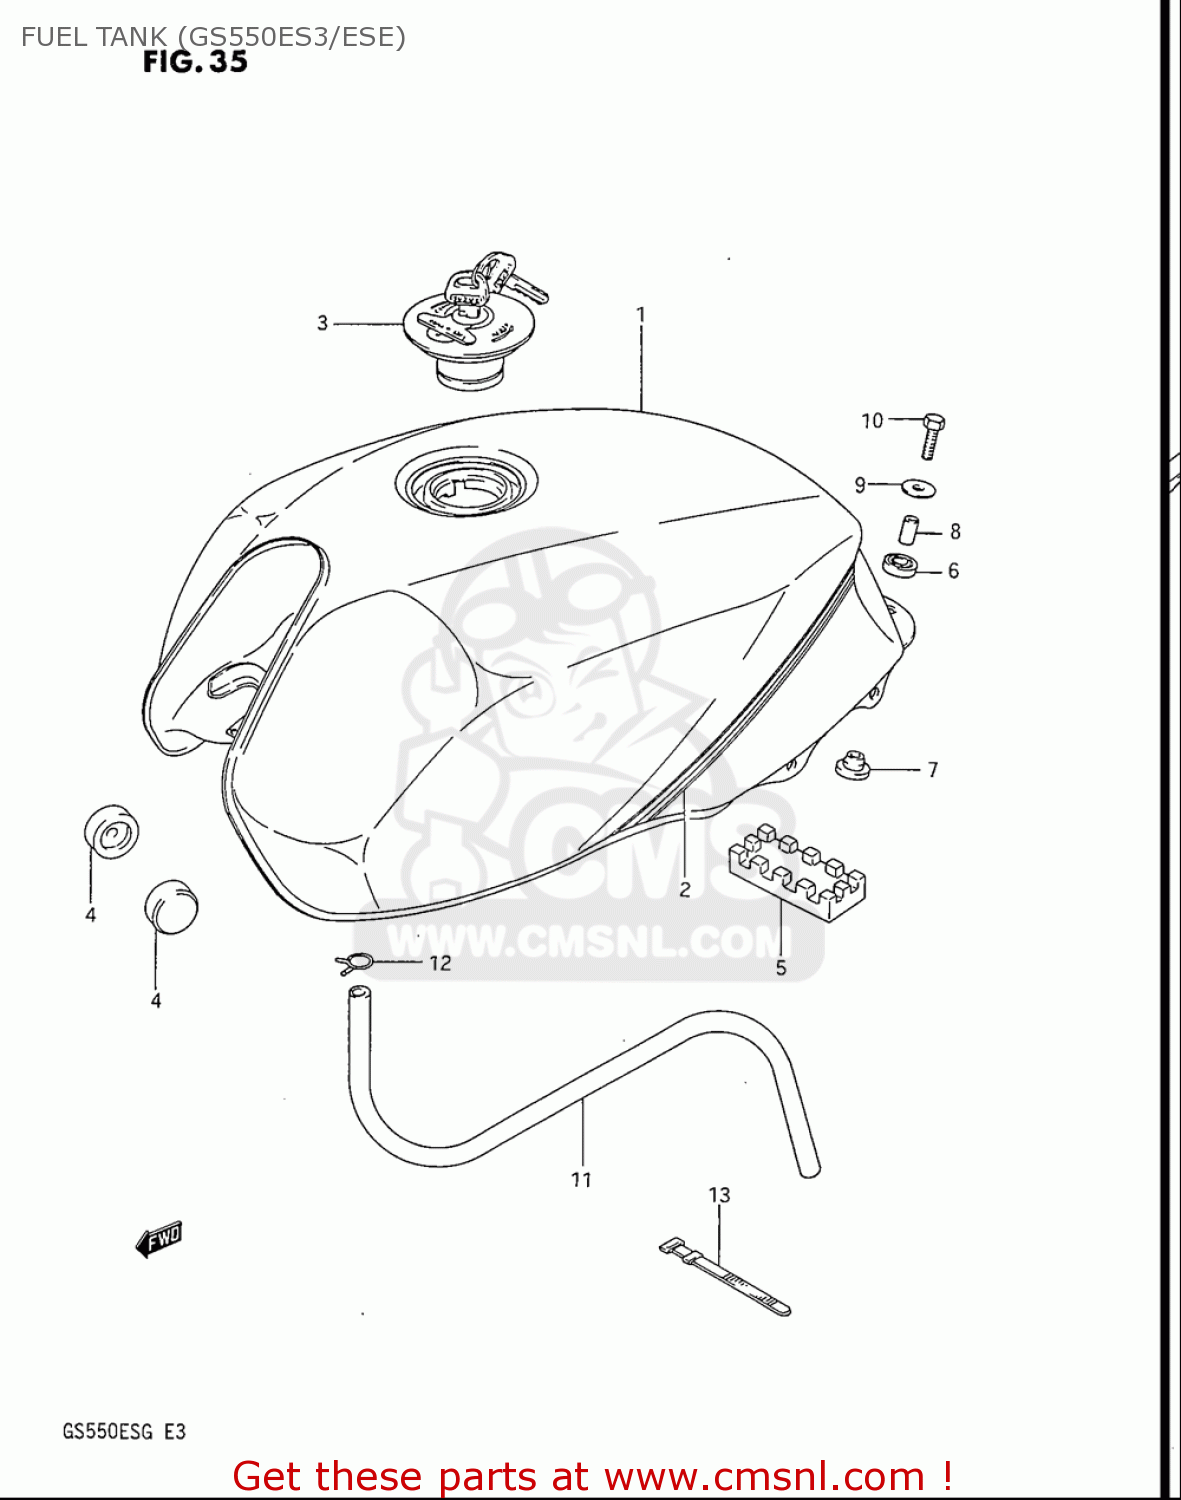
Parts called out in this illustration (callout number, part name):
1	TANK ASSEMBLY,FUEL
3	CAP ASSY,FUEL TANK
4	CUSHION
6	CUSHION
7	CUSHION
8	SPACER(6.5X9X20)
9	WASHER(6.5X24X1.6)
10	BOLT
11	HOSE(5X8.2X2000)
12	CLIP
13	CLAMP(L:187)
